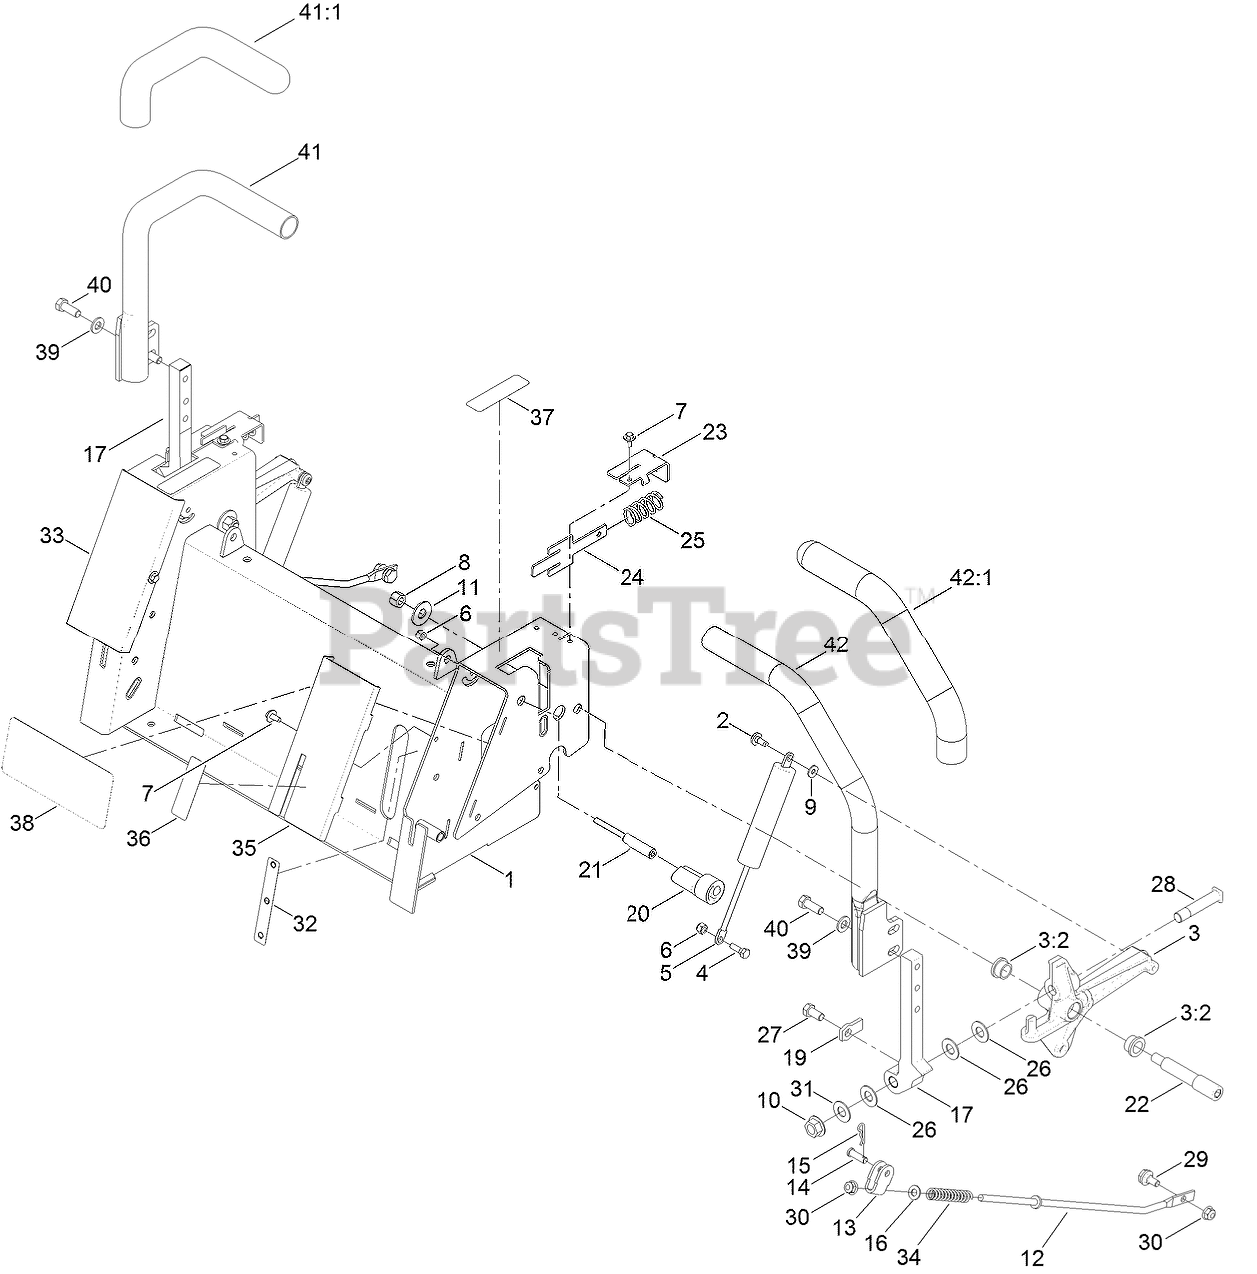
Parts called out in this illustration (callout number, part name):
1	BOX-CONTROL
2	SCREW-SHOULDER
3	ACTIVATOR ARM ASM
3:2	BUSHING
4	BOLT-SHOULDER
5	DAMPER
6	NUT-LOCK, NI
7	SCREW-HHFTF
8	NUT-LOCK, NI
9	WASHER
10	NUT-HF
11	WASHER-FLAT
12	ROD-CONTROL
13	BRACKET-CONTROL
14	PIN-CLEVIS
15	PIN-COTTER
16	WASHER-PLAIN
17	Arm-Actuator
19	TAB-STOP
20	ECCENTRIC
21	SCREW-ECCENTRIC
22	BOLT-SHOULDER
23	BRACKET-RETURN
24	PLATE-RETURN
25	SPRING-COMPRESSION
26	WASHER-PIVOT
27	SCREW-HH
28	BOLT-SHOULDER
29	BOLT-SHOULDER
30	NUT-HF, NI
31	WASHER-TEFLON
32	DECAL-FILL, FUEL
33	COVER-CONTROL, RH
34	SPRING-RETURN, NEUTRAL
35	COVER-CONTROL, LH
36	DECAL-BRAKE, PARKING
37	DECAL-CONTROL, MOTION
39	WASHER-FLAT
40	SCREW-HH
41	RH LEVER/GRIP ASM
41:1	Grip-Control, Motion
42	LH LEVER/GRIP ASM
42:1	Grip-Control, Motion
